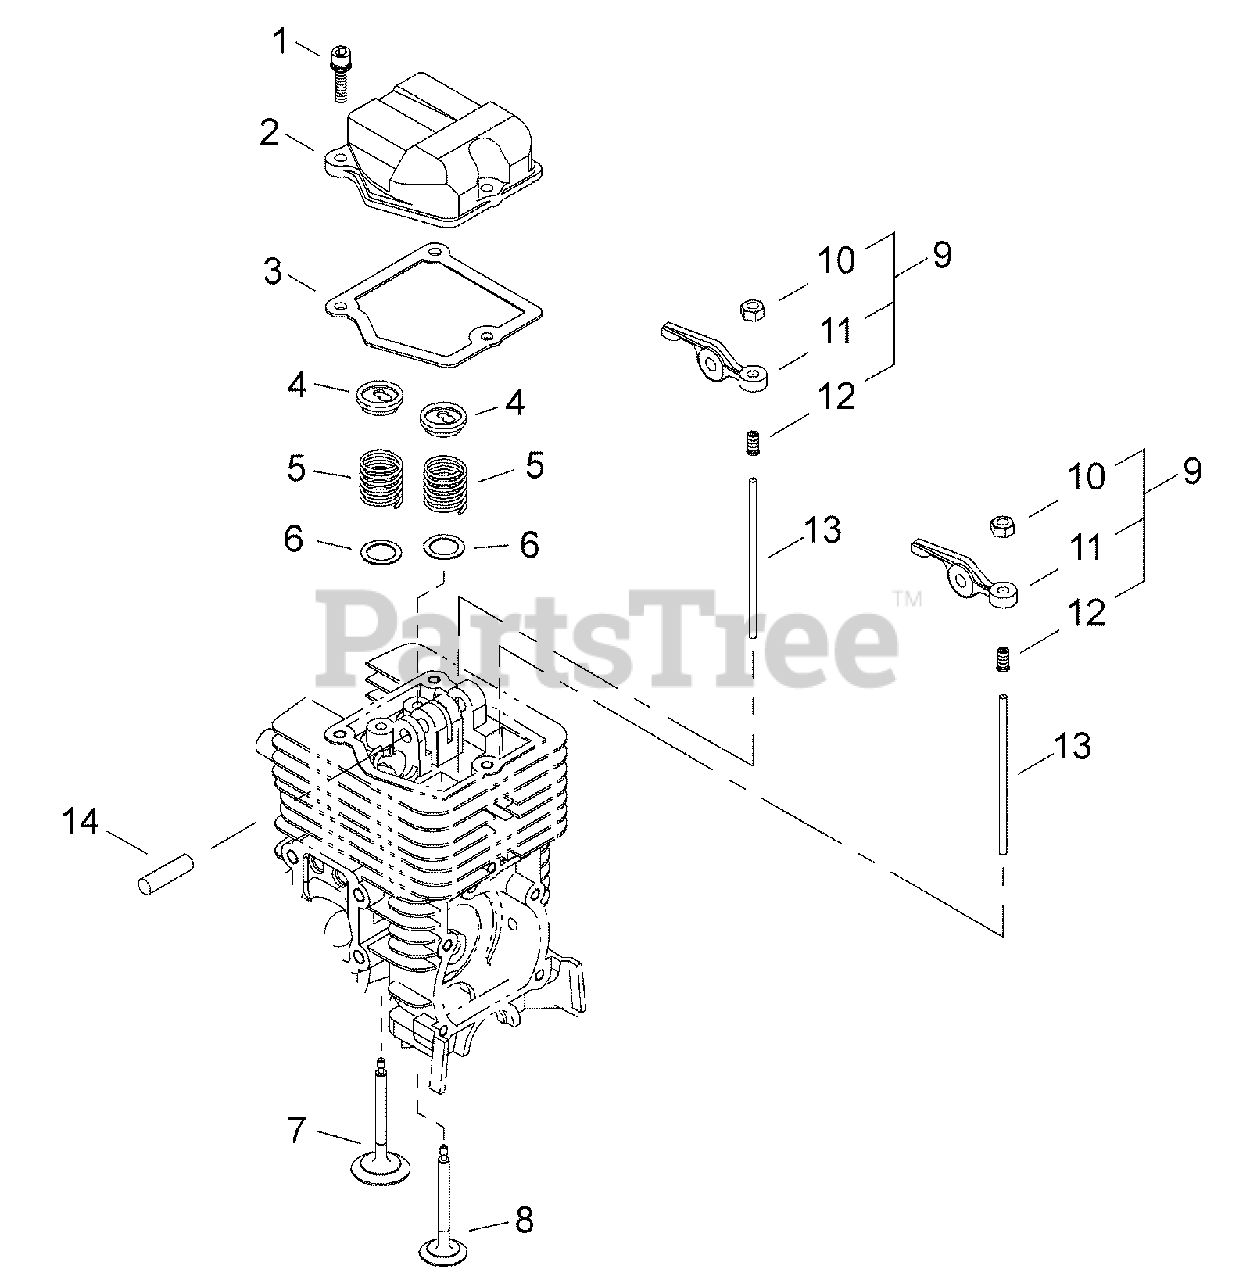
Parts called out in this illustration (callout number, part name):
1	SCREW - 4X12
2	COVER, ROCKER ARM
3	GASKET
4	RETAINER, VALVE
5	SPRING, VALVE
6	WASHER, VALVE - 9
7	VALVE, INTAKE
8	VALVE, EXHAUST
9	ROCKER ARM ASSY
10	LOCKNUT, ADJUSTER
11	ARM, ROCKER
12	SCREW, ADJUST
13	PUSHROD
14	SHAFT, ROCKER ARM - 5X31.8
